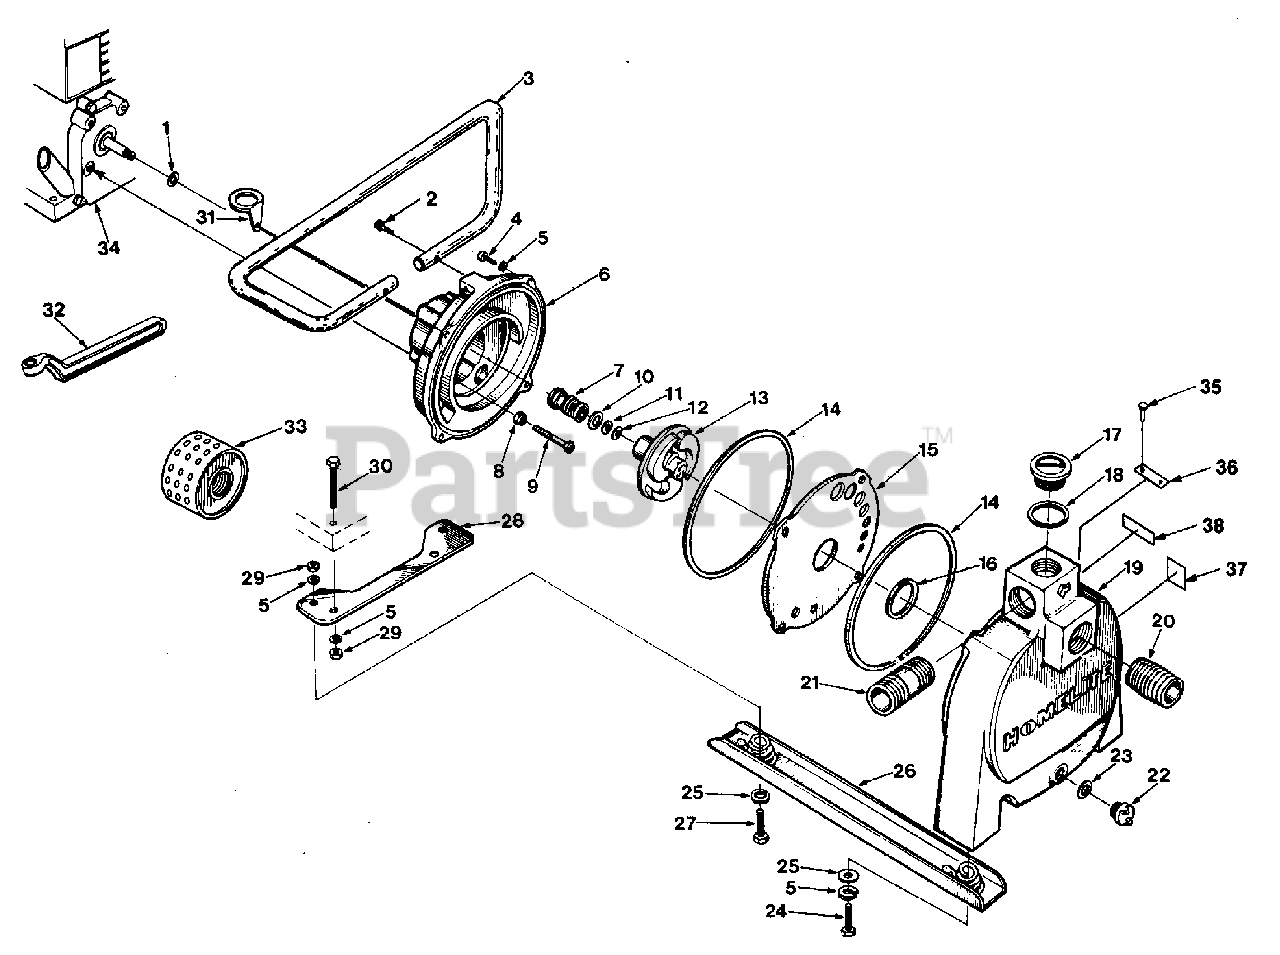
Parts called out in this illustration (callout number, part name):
1	WASHER- Slinger
2	SCREW- Hex hd., 1/4-20 x 1/2"
3	HANDLE- Carrying
4	SCREW- Hex hd., 5/16-18 x 1 1/4"
5	WASHER- Lock, 5/16"
6	HOUSING- Impeller
7	SEAL ASSEMBLY
8	WASHER- Sealing
9	SCREW- Hex hd., 5/16-24 x 21/4"
10	SHIM- Seal, .010"
11	WASHER- Flat 5/16"
12	SHIM- Impeller, .010"
13	IMPELLER
14	GASKET- Large
15	PLATE- Wear
16	GASKET- Small
17	PLUG- Filler
18	GASKET- Wing plug
19	HOUSING- End (aluminum)
20	NIPPLE- Suction, 2" NPT x 2" long
21	NIPPLE- 2" NPT x 3 1/2 long
22	PLUG- Drain
24	SCREW- Hex hd., 5/16-18 x 3/4"
25	WASHER- Flat, 5/16"
26	SKID ASSEMBLY
27	SCREW- Hex hd., 5/16-18 x 1 1/4"
28	BAR- Mounting
29	NUT- Hex 5/16-18
30	SCREW- Hex hd., 5/16-18 x 1 1/2"
31	HOLDER- Spanner wrench
32	WRENCH- Spanner
33	STRAINER- Suction, 2"
34	ENGINE- Briggs & Stratton (Models 111S2-1 & 111S2-1A)
35	TACK- Metal (Model RS2)
36	PLATE- Warning
37	DECAL- Class
38	DECAL- Fill pump
